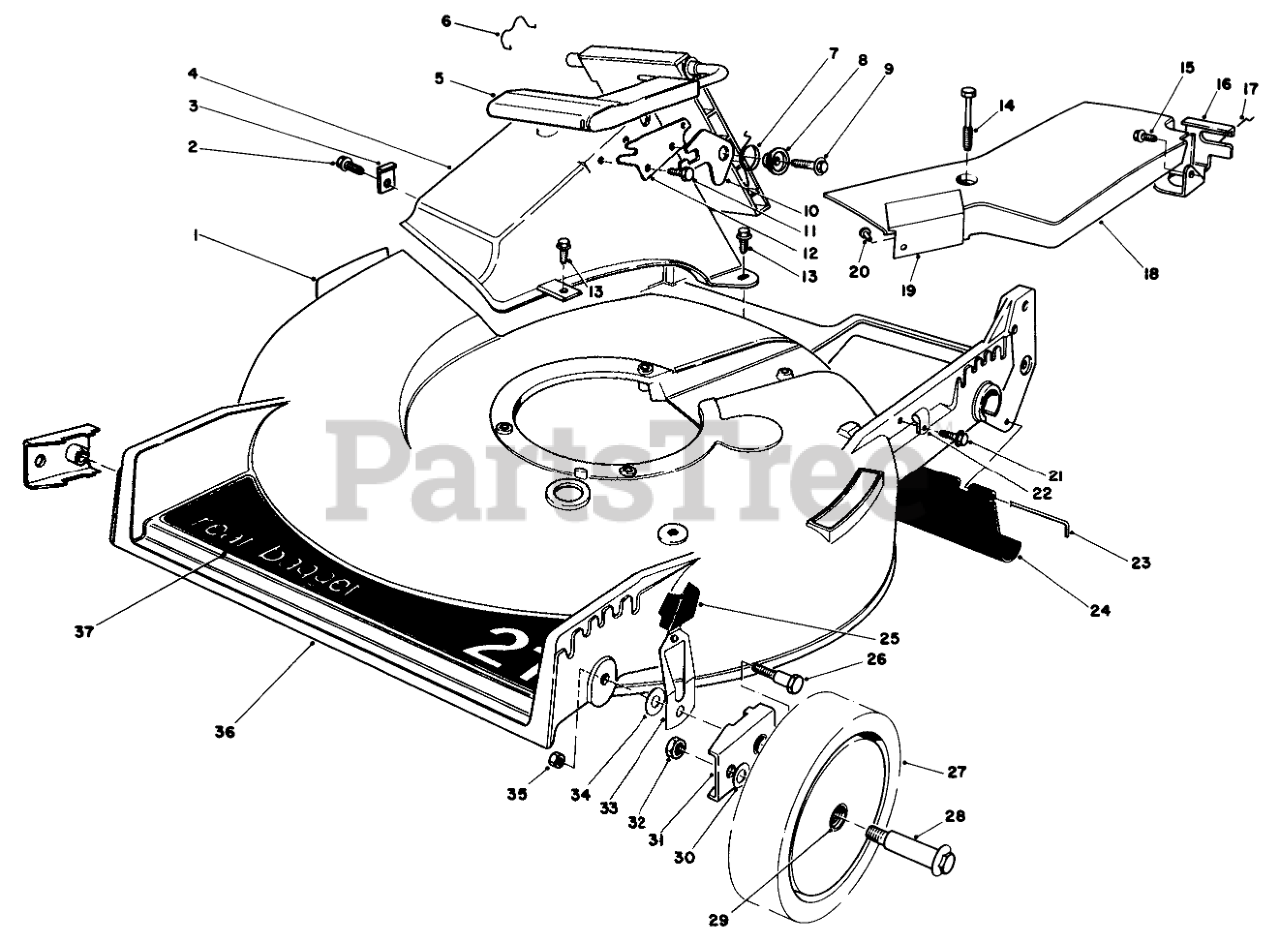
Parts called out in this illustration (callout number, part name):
1	DECAL-DANGER
2	SCREW
3	TUNNEL CLIP
4	Tunnel Discharge
5	Discharge Door Assembly
6	DOOR RET SPRING
7	TORSION SPRING
8	DOOR SPACER
9	SCREW-HWH
10	SAFETY LATCH
11	SCREW-PLASTITE
12	DOOR LATCH PLATE
13	SCREW-HWH
14	SCREW-HHFTF
15	SCREW-TAPTITE
16	Bracket-Traction Adj.
17	RETAINER-CABLE
18	Belt Cover Assembly (Incl. Ref. #19 & 20)
19	HEAT SHIELD
20	RIVET-HEAD, FLAT
21	SCREW
22	CLAMP-CABLE
23	Rod Shield
24	SHIELD - TRAILING
25	KNOB-ARM
26	PIVOT SCREW
27	Wheel & Tire Assembly (Incl. Ref. #29)
28	WHEEL BOLT
29	BUSHING
30	WASHER
31	HP PIVOT ARM ASM
32	NUT-LOCK
33	Spring Arm
34	WASHER-PIVOT
35	NUT-LOCK, NI
36	Housing (Incl. Ref. #1)
37	DECK DECAL
